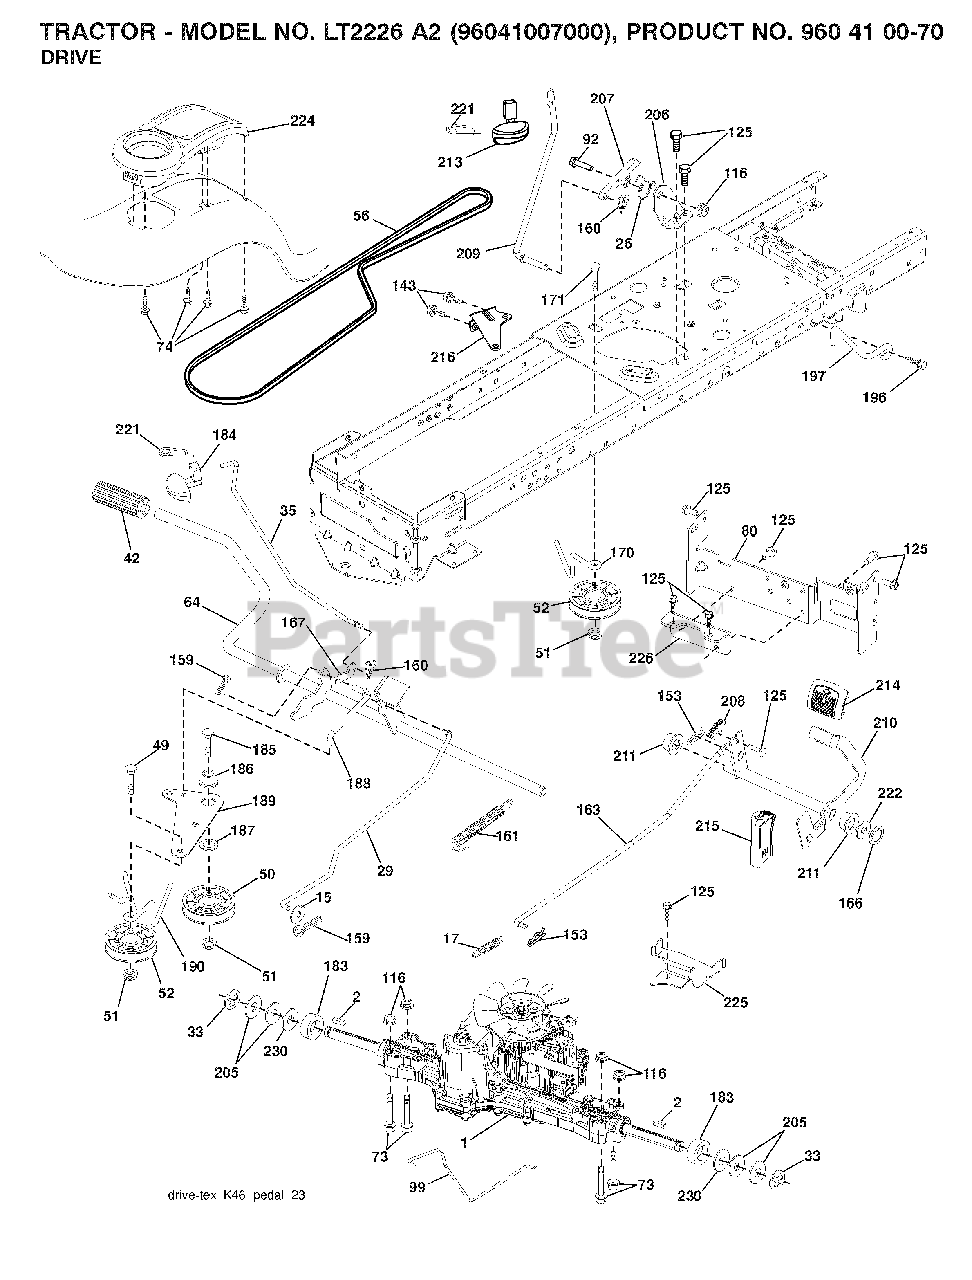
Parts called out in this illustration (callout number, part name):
2	SQUARE KEY
17	SPRING.BRAKE.K46.GREEN
26	SPRING.RETURN.CRUISE
29	ROD.BRAKE.K46
33	E-RING LT
35	ROD.BRKAE.PARKING.STEALTH
42	PEDAL COVER T
49	BOLT
50	IDLER.FLAT.910.OFFSET
51	NUT LOCK FLG 3/8-16 UNC
52	IDLER.V-GROOVE.910.OFFSET
64	SHAFT.ASM.PEDAL.BRK.CNTR
73	BOLT HEX 5/16-18 GR 5
74	SCREW.HI-LO.CONSOLE
80	STRAP TORQUE.ASM.K46/18"TEX
92	BOLT
99	ROD.SPRING.BYPASS.K46.LT.Z
116	NUT LOCK HEX FLANGE 5/16-18
125	SCREW
153	RETAINER M
159	COTTER PIN
160	RETAINER CLIP
161	SPRING, RETURN LT
163	ROD.CONTROL.PEDAL.K46
166	NUT.PUSH.625.2006
167	LATCH.BRAKE.SPRING
170	KEEPER.V-IDLER.CENTER.
171	BOLT
183	SPACER AXLE
184	HANDLE.PRKG.BRAKE.STLTH.TX.RED
186	SPACER.RETAINER
187	WASHER 12/32X2X10GA
188	LINK.CLUTCH.GROUND.DRIVE
189	BELLCRANK.GROUND.DRIVE.TEX.
190	KEEPER.BELLCRANK.DRIVE
196	SCREW 3/8-16X1
197	LINK.CLUTCH.ANIT-ROTAT
206	BRKT.MOUNT.LATCH.CRUIS
207	LATCH.CONTROL.CRUISE
208	GEAR.SECTOR.CONTROL.CR
209	ROD.CONTROL.CRUISE.STEALTH.TEX
210	ROCKER.ASM.PEDAL.CONTR
211	BEARING.NYLON
213	KNOB.CONTROL.CRUISE
214	PEDAL.FORWARD.TEX.GT.4
215	PEDAL.REVERSE.TEX.GT.4
216	BRACKET.PULLEY.IDLER.W/TEX
221	RETAINER.SPRING.CLIP.H
222	WASHER 21/32 X 1-1/4 X 10 GA.
224	CONSOLE.TOOLBOX.PCH.ERGO.BLACK
225	KEEPER.BELT.TRANSAXLE.K46
226	BRACKET.MOUNT.TORQUE.K46.TLT
230	WASHER.HARDENED
